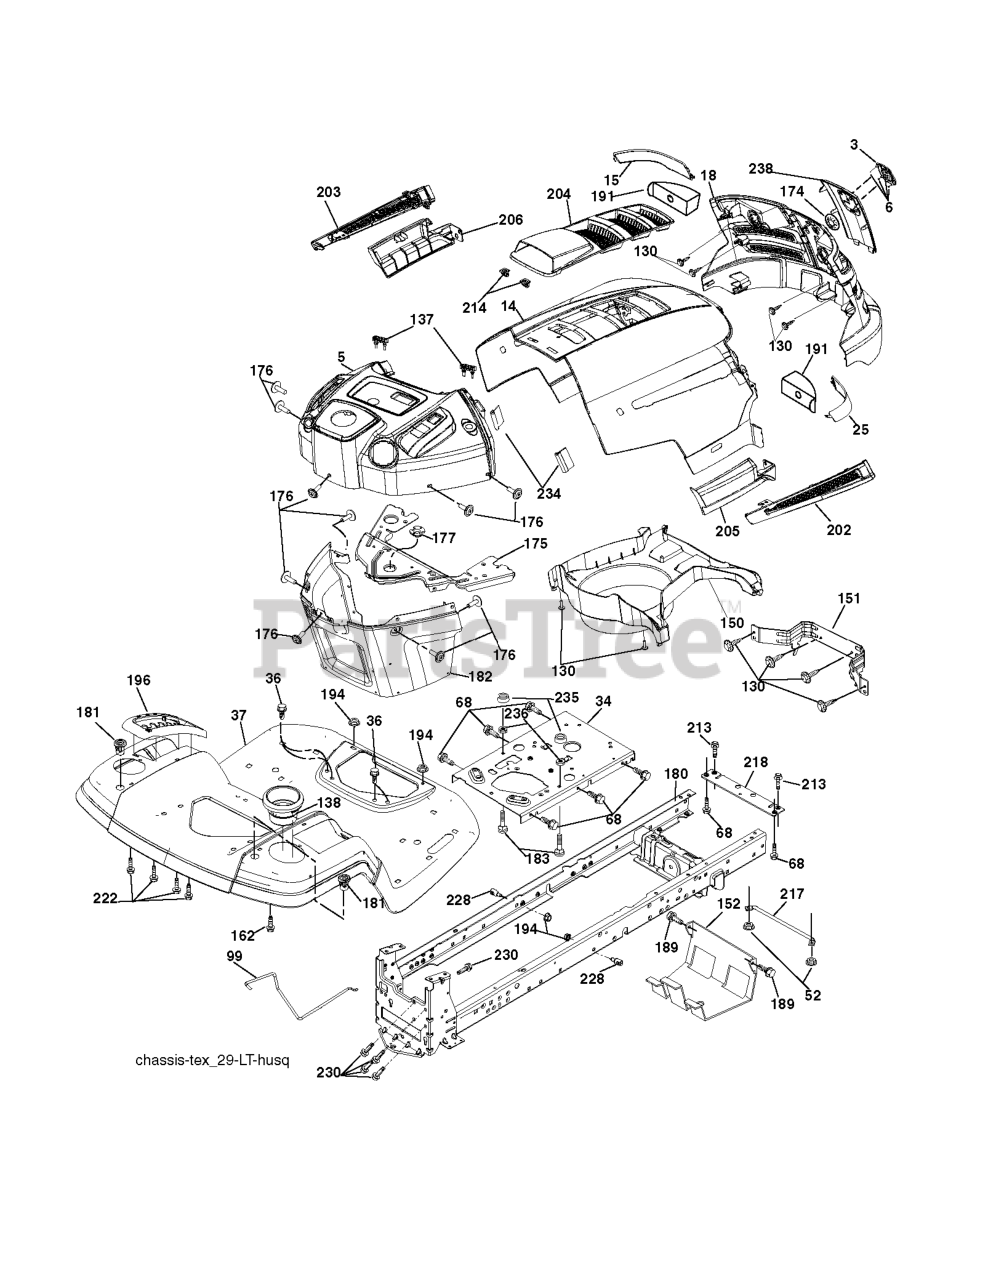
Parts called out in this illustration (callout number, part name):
3	RP LOGO
14	HOOD
15	LENS.HUSQVARNA LT.LH
18	RP GRILLE/LENS ASM.
25	LENS.HUSQVARNA LT.RH
34	PLATE.ENGINE.WELDED.CHASSIS
36	SCREW 5/16"
37	FEND/FTRST.PCH.CPH.NFW
52	LOCKNUT
68	Screw 5/16-18 x 1/2 Hex, Self Tapping 5/16-18 x 1/2
99	ROD ASM BYPASS
130	SCREW
137	BUMPER DASH
138	CUPHOLDER.TL.TEX.418
151	BRACKET PIVOT
152	SHIELD.BROWNING.W/TEX
162	SCREW.HI-LO.CONSOLE
175	CROSSMEMBER
176	SCREW.#10-24X5/8.RN.QU
177	BUSHING STEERING
180	CHASSIS
181	BUSHING.MNT.FEND.CRGO.
182	DASH LOWER
183	BOLT.5/16-18X1-1/4 FULL.THREAD
189	SCREW
191	INSERT REFLECTIVE
194	NUT LOCK HEX FLANGE 5/16-18
196	CONSOLE.ASM.DECK.LIFT.
202	VENT SIDE HOOD RH
203	VENT SIDE HOOD LH
204	VENT TOP HOOD
205	SKIRT SIDE RH
206	SKIRT SIDE LH
213	BOLT
214	CLIP.RETAINER.TINNER.
217	ROD PIVOT CHASSIS/HOOD
218	X-PIECE.HOOD.STOP.NON/
222	SCREW.1/4-20X5/8
228	STUD.FASTNER.W/ANTI-ROTATE
230	SHOULDER BOLT 5/16-18TT
234	BUMPER.HOOD.TEX.HUSQVARNA
235	SPACER FENDER
236	NUT.CENTERLOCK.5/16-
238	TRIM
